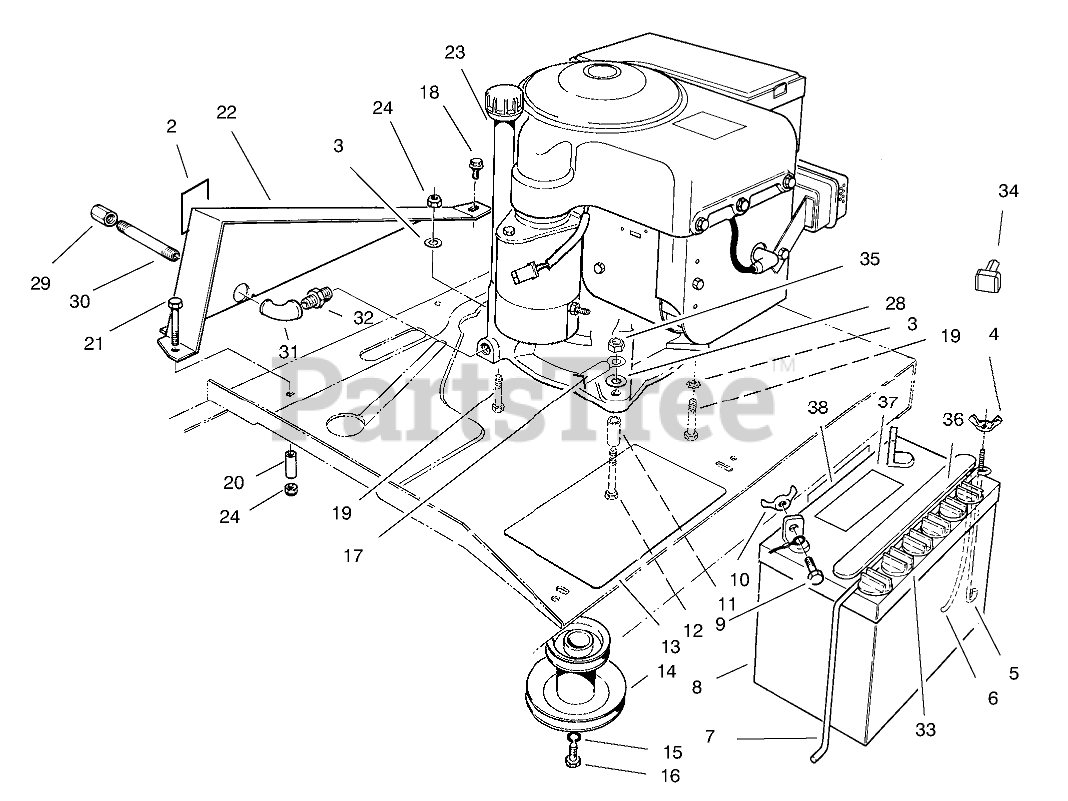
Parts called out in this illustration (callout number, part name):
3	WASHER-PLAIN
4	NUT-WING
5	POST-BATTERY
6	TUBE-BATT DRAIN/80-2600
7	HOLDDOWN-BATTERY
8	Battery
9	SCREW-HH
10	NUT-WING
11	SPACER-PIVOT
12	SCREW-HH
13	PAD-SKID, ANTI
14	PULLEY - ENGINE
15	WASHER-FLAT
16	SCREW-HH
17	ASM - CABLE WIRE
18	SCREW-HWHTF
19	SCREW-HH
20	GUIDE-BELT
21	SCREW-HH
22	GUIDE-CHAIN
23	Engine-8 H.P.B & S
24	NUT-LOCK, NI
28	WASHER-LOCK
29	CAP-PIPE
30	NIPPLE-PIPE
31	ELBOW-STREET
32	BUSHING-PIPE
33	CAP-BATTERY
34	BOOT-TERMINAL
35	NUT-HEX, SIDE DEFORM
36	DECAL - DANGER
37	DECAL-DANGER
38	DECAL-BATTERY
